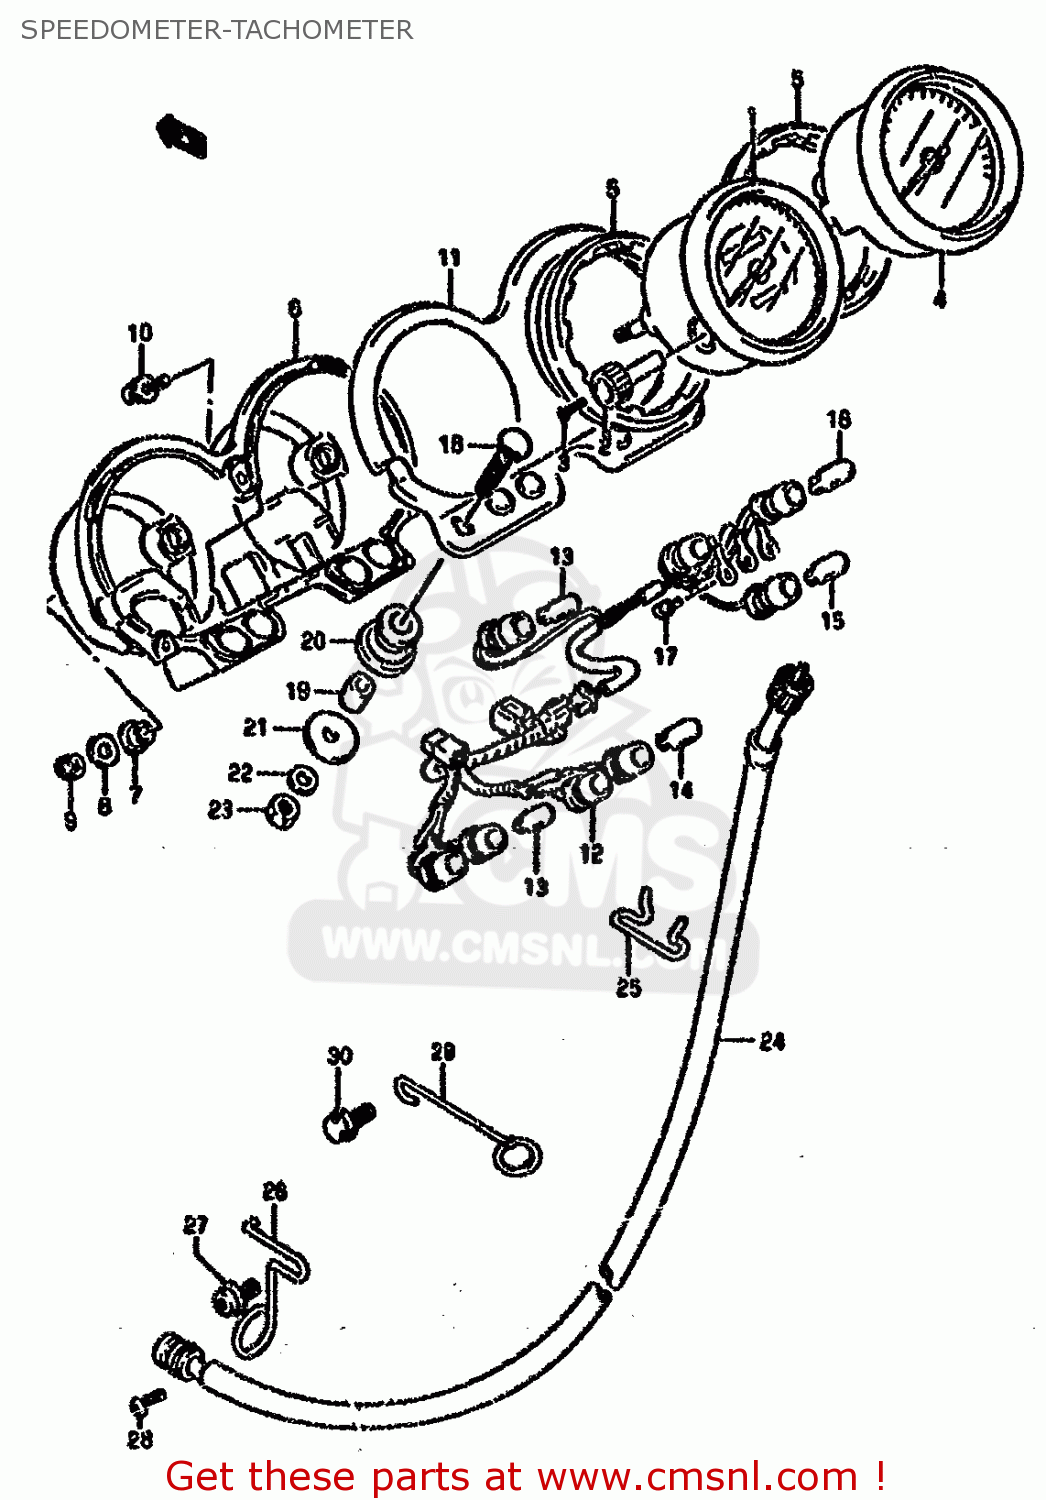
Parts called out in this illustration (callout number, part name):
1	SPEEDOMETER
2	KNOB,TRIP
3	ROTOR,SPEED
4	TACHOMETER
5	DAMPER
6	COVER
7	CUSHION
8	WASHER
9	NUT
10	SCREW
11	BRACKET,METER
12	SOCKET & HARNESS ASSEMBLY
13	BULB(12V3.4W,T10)
14	BULB(12V1.7W,T10,WB121)
15	BULB(12V3W,T6.5)
16	BULB(12V1.7W,T6.5)
17	SCREW
18	BOLT(6X34)
19	SPACER (6.1X10X15.7)
20	CUSHION,METER BRACKET
21	WASHER (6.5X29X1.6)
22	LOCK WASHER
23	NUT 6MM
24	CABLE ASSY,SPEEDOMETER
25	CLAMP,SPEEDOMETER CABLE
26	CLAMP,SPEEDOMETER CABLE
27	BOLT
28	SCREW
29	GUIDE,SPEEDOMETER CABLE NO.3
30	BOLT
